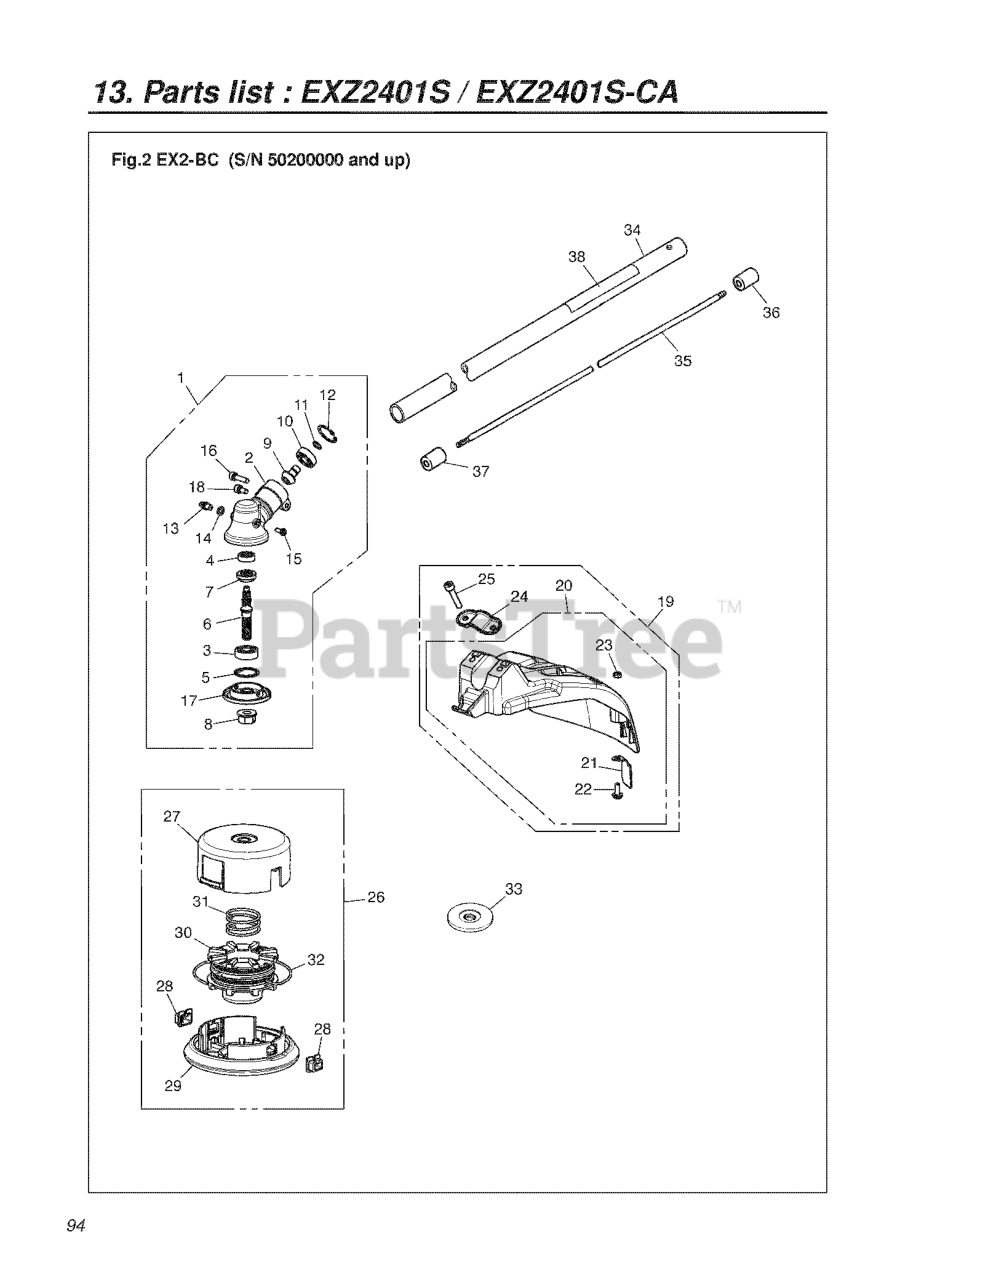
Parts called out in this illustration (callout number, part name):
1	GEARCASE ASSY.
2	GEARCASE
4	BEARING (RPLS T330013520)
5	RING,SNAP M26x1.2 RP-318013340
15	BOLT
17	HOLDER(A)
19	GUARD ASSY. (RPLS T3195-24002)
20	GUARD COMP.
21	BLADE (RPLS T300224120)
25	BOLT, TORX
26	4" TAP TRIMMER HEAD PT104
27	CASE (RPLS T318915111)***
28	EYELET
29	COVER (RPLS T318915131)
30	HOLDER, CORD (RPLS T318915141)
33	HOLDER (B)
